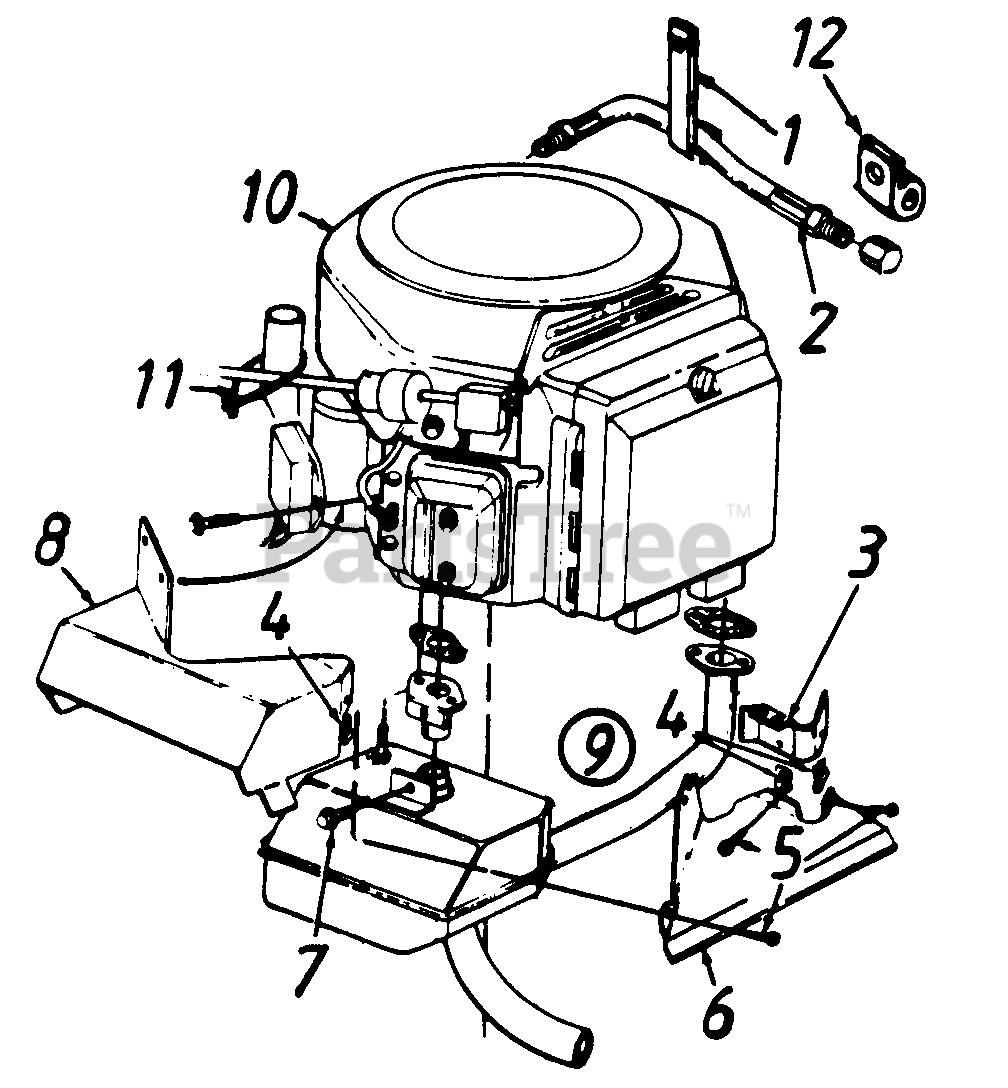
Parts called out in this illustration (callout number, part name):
2	Hydraulic Hose 13" Lg.
3	Front Heat Shield Ext.
4	Speed Nut #10-24 Thd.
5	Hex B-Tap Scr. #10 x .38" Lg.
6	Front Heat Shield
7	Hex Wash. Hd. TT-Tap Scr. 1/4-20 x .5" Lg.
8	Muffler Heat Shield
9	Muffler Ass'y. Comp.
10	Engine
11	Cable Tie
